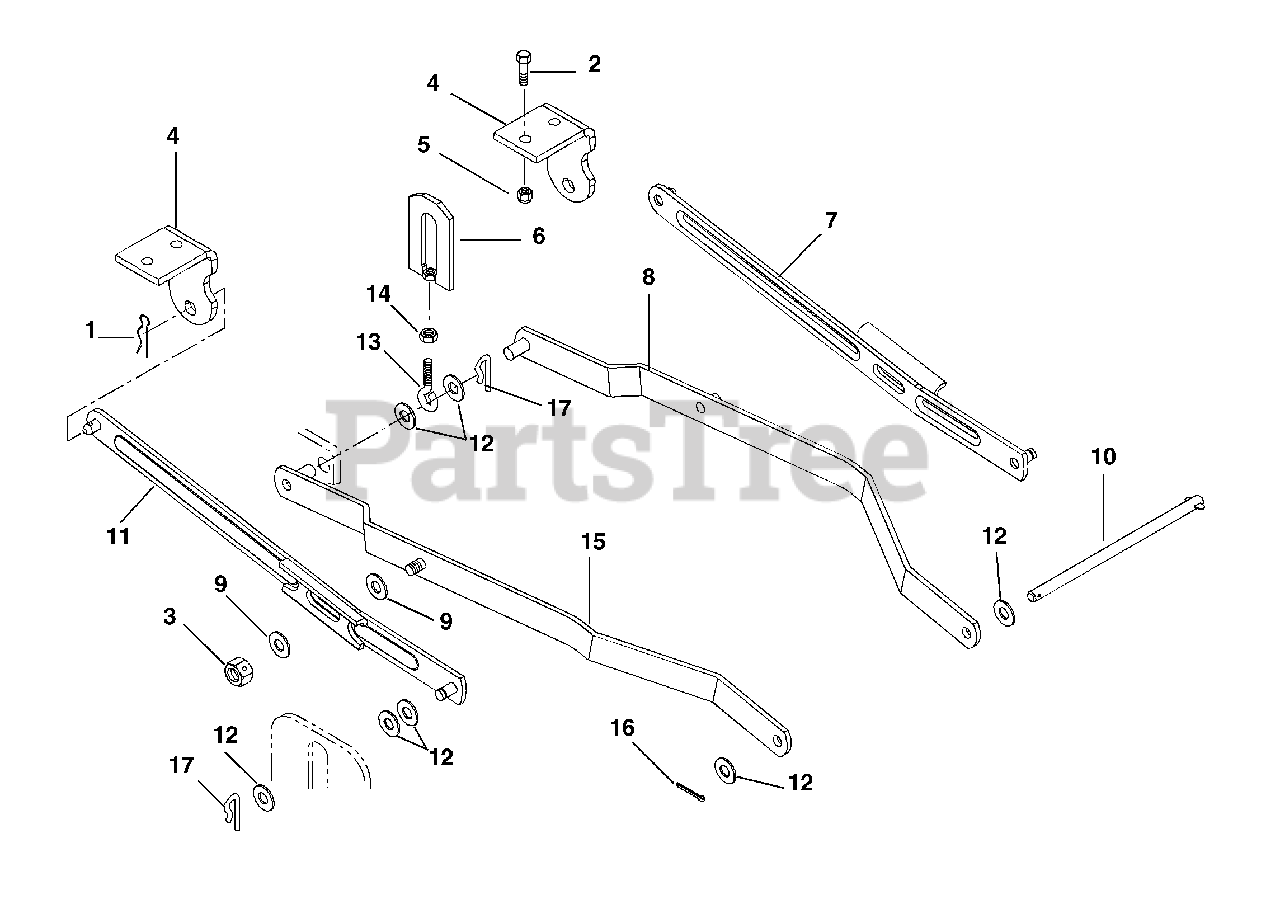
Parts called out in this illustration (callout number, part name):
1	PIN-HAIR-EXT .12X.31X2.37 YWZC
2	@BLT-HEX .38-16X.75 GR5 YWZC
3	@NUT-LK-CTR .62-11 YWZC
4	REAR HANGER
5	@NUT-LK-CTR .38-16 YWZC
6	WELDMENT, ADJUSTMENT LINK
7	HANGER, REAR LH
8	ARM, LIFT LH
9	@WSHR-FL-STL.656X1.31X.095 YWZ
11	HANGER, REAR RH
12	WSHR-FL-STL .531X1.250X.10 YWZ
13	BLT-EYE .375-16X2.50 YWZC
14	NUT-HEX-JAM .375-16 YWZC
15	ARM, LIFT RH
16	@PIN-CTR .16X1.00 EXTPRSQCT YZ
17	CLIP, SPRING
